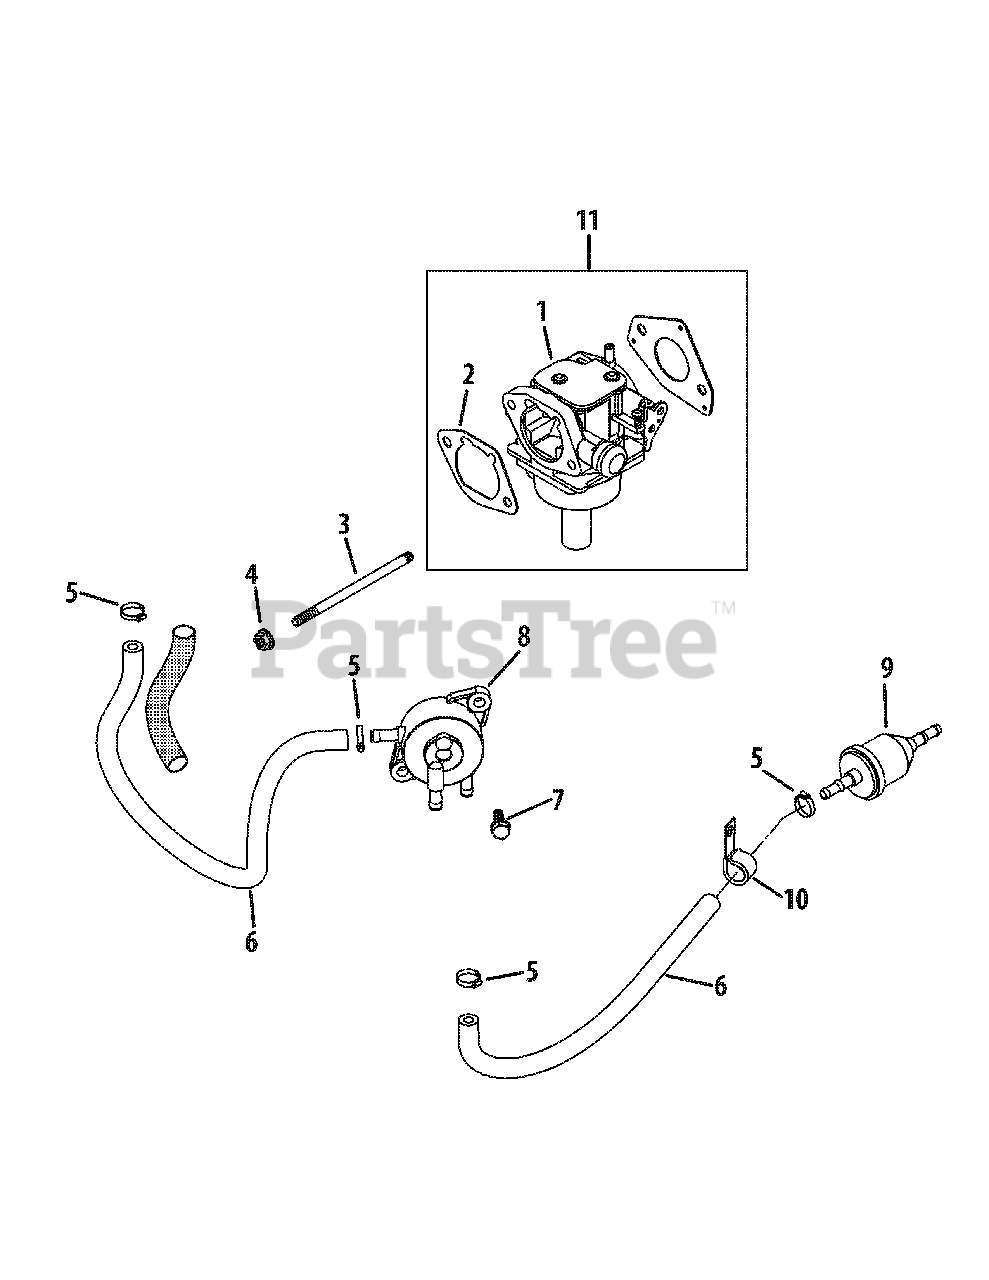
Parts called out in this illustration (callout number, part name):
1	Carburetor Gasket
2	Air Cleaner Base Gasket
3	Stud, M6 x 1.0 x 106
4	Flange Nut, M6 x 1.0
5	Hose Clamp, 1.2
6	Fuel Line
7	Tap Screw, M6 x 1.7 x 18
11	Carburetor Kit, 19mm KEIHIN (Inc.#2 & 3)
